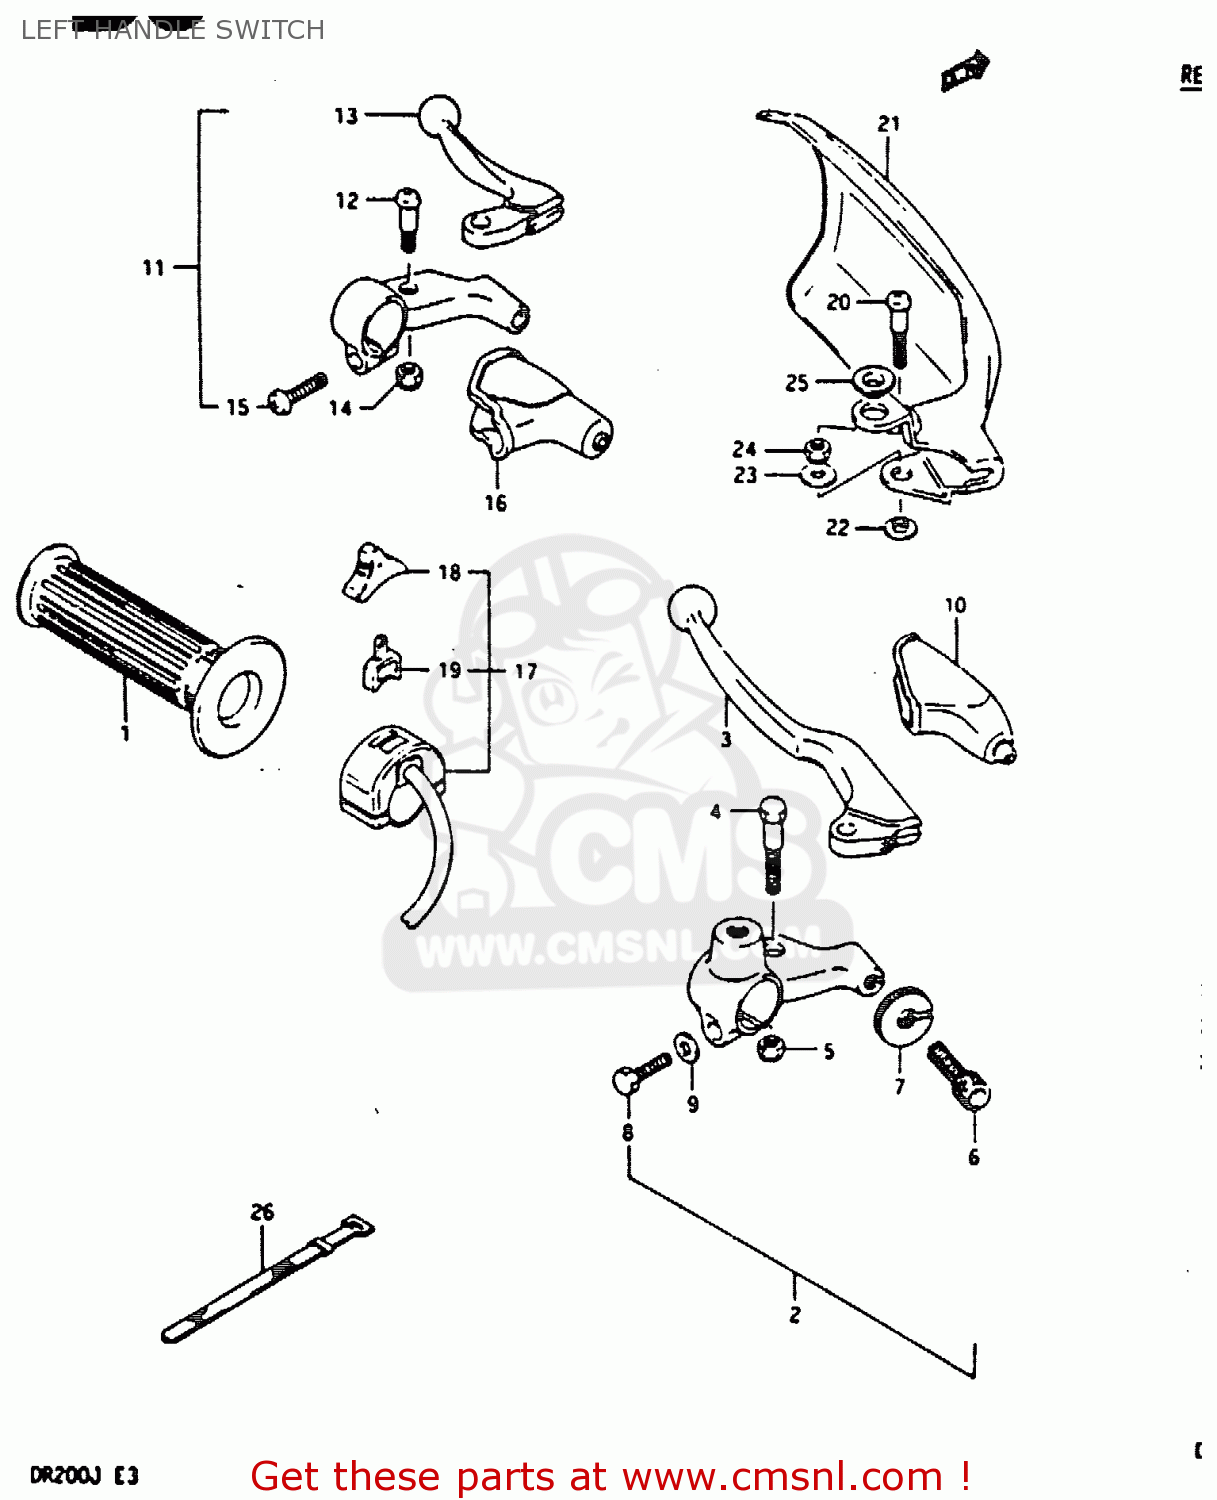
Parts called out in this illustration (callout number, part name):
1	GRIP,L
2	LEVER ASSEMBLY,CLUTCH
3	LEVER,CLUTCH
4	BOLT,LEVER PIVOT
5	NUT
6	ADJUSTER,CABLE
7	NUT,CABLE ADJUSTER LOCK
8	BOLT
9	WASHER
10	COVER,CLUTCH LEVER
11	LEVER ASSEMBLY,DECOMPRESSION
12	BOLT,LEVER
13	LEVER,DECOMP
14	NUT
15	SCREW
16	COVER,DECOMP LEVER DUST
17	SWITCH ASSY,LIGHTING
18	KNOB,LIGHTING & DIMMER
19	BLOCK,LIGHTING/DIMMER
20	BOLT,LEVER PIVOT
21	COVER,KNUCKLE,L
22	WASHER
23	WASHER(6.5X16X1.2)
24	NUT 6MM
25	WASHER
26	CLAMP(L:120)
